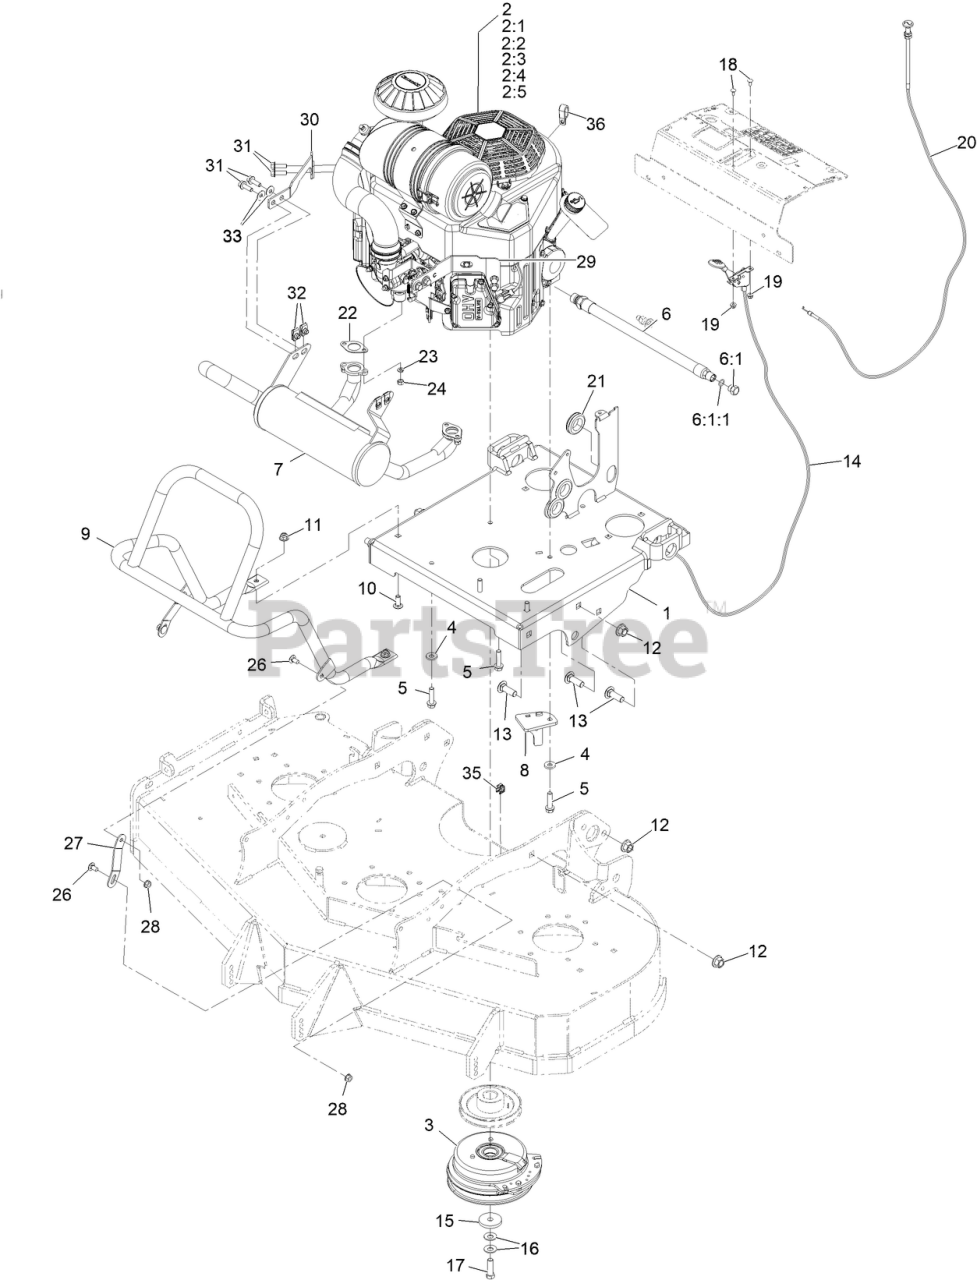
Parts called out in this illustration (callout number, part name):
1	ASM-ENGINE DECK
2:5	SPARK PLUG
3	Clutch, Cms-175
4	WASHER-BELLEVILLE
5	SCREW-HWH
6	ASM, ENGINE OIL DRAIN HOS
6:1	PLUG-HH
6:1:1	O-RING
7	MUFFLER-KAWASAKI
8	ASM-CLUTCH ANCHOR
9	Tube-Guard Muffler
10	SCREW-CARR
11	NUT-HF, NI
12	Nut-Lock 1/2-13
13	Screw-CARR
14	CONTROL,THROTTLE
15	WASHER-CLUTCH
16	WASHER-SPRING
17	SCREW-HH 7/16-20 X 1 1/2 W/LOCTITE
18	BOLT-CARR
20	CABLE-CHOKE
21	GROMMET
22	GASKET-EXHAUST
23	WASHER-LOCK
26	SCREW-CARR
27	Strap, Muffler Guard
29	BRACKET-MUFFLER, FRONT
30	BRACKET-MUFFLER, REAR
31	SCREW-HHF
33	WASHER-BELLEVILLE
35	Clip-Edge W/Tie, Perpendicular
36	CLAMP-R, DOUBLE TUBE
